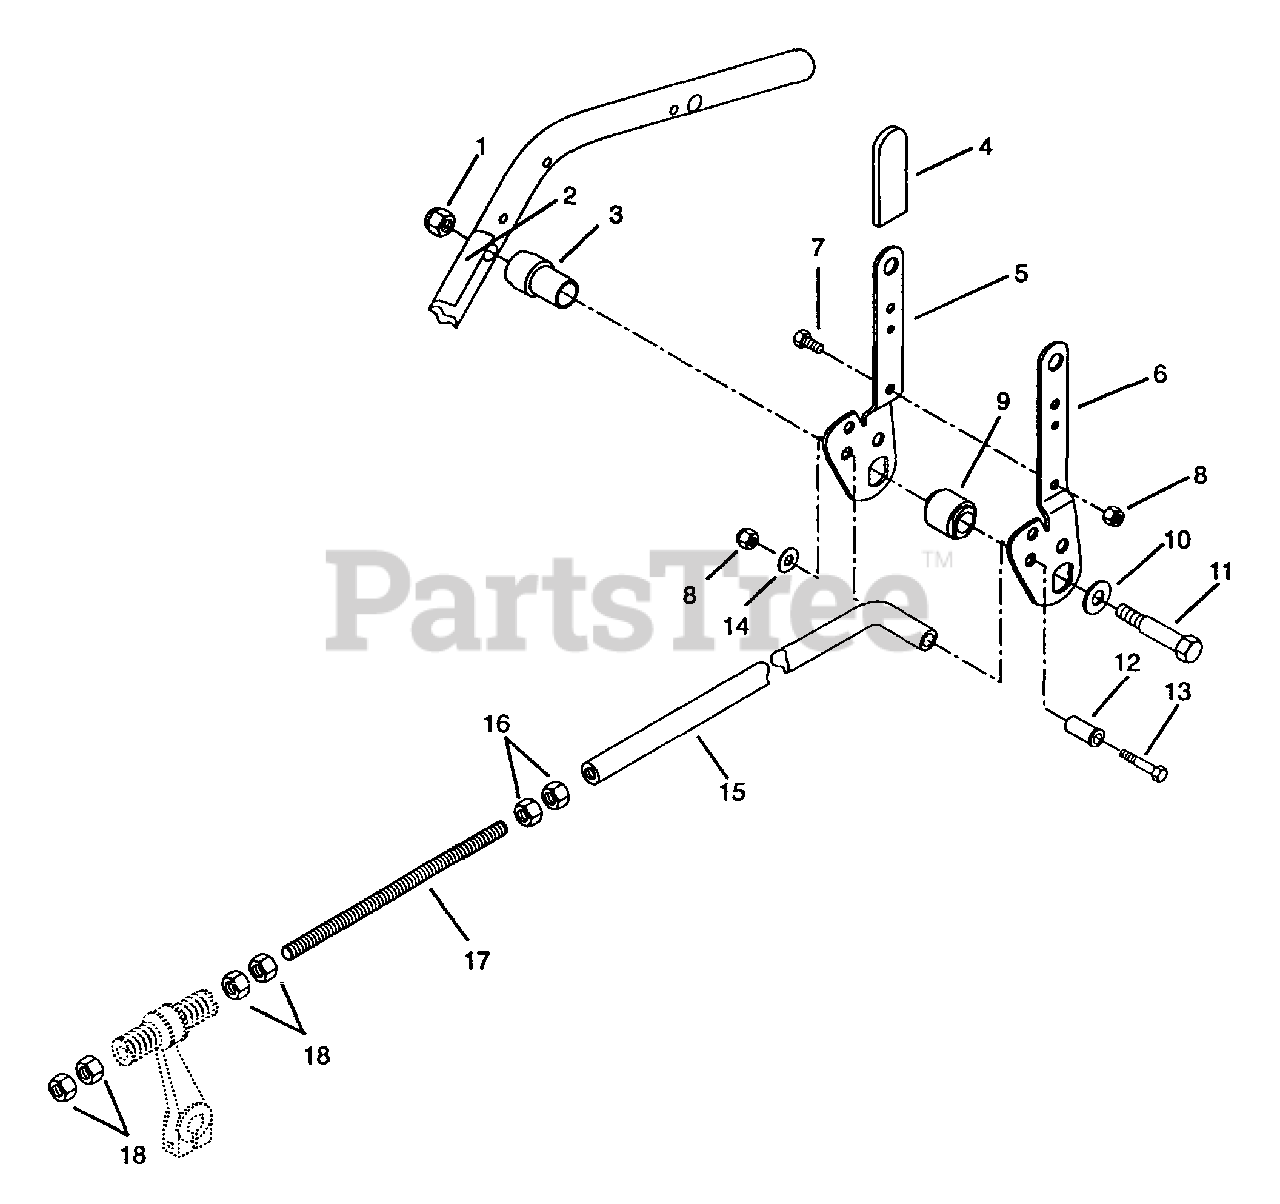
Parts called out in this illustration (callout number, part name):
1	Nut-Locking-Nylon .375-16 Grade 2
2	Decal, Gear Shift
3	Pivot, Hand Lever Left Hand
4	Grip, Handle
5	Handle, Control Right Hand
6	Handle, Control Left Hand
7	Bolt-Hex .25-20 x .63
8	Nut-Locking-Nylon .250-20 Grade 2
9	Bushing Flange .751 x 1.13 x 1.07
10	Washer-Flat-Steel.531 x 1.062 x.095
11	Bolt-Hex.38-16 x 3.5
12	Bushing-Flange.257 x.38 x 1.080
13	Bolt-Hex.25-20 x 1.50 Grade 5
14	Washer-Flat-Steel .281 x .620 x .065
15	Rod, Control Hi-Lo
16	Nut-Hex .375-16 Grade 2
17	Rod, Extension
18	Nut-Jam .375-16
